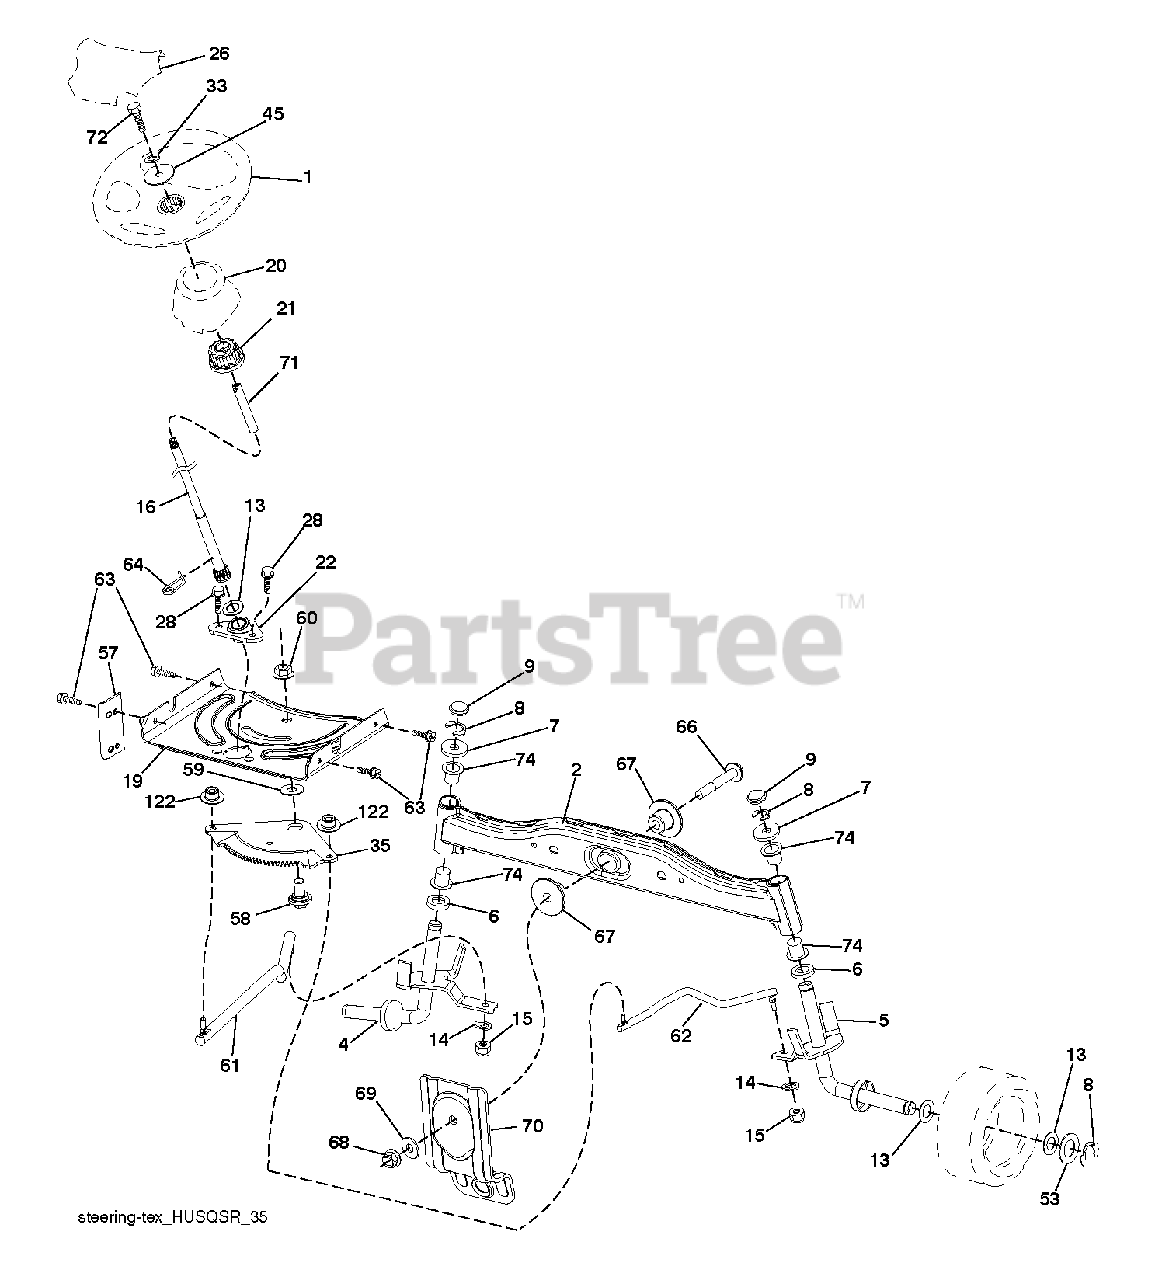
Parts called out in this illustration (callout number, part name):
1	WHEEL.STEER.HUSQ.SR.498.OVMLD
2	AXLE HALF ASM-WELDED
4	SPINDLE.STEERING.ASM.LH.13".TI
5	SPINDLE.STEERING.ASM.RH.13".TI
6	THRUST WASHER
9	CAP.SPINDLE.BLACK
14	WASHER, LOCK 3/8
15	NUT CROWNLOCK 3/8-24
16	SHAFT.STEER.3/4.PLATED.TEX
19	PLATE.STEER.DDL.NLT/NG
20	STEERING.BOOT.HUSQ.LT
21	ADAPTER, WHEEL STNG..
22	STEERING.SUPT.LOWER.
26	INSERT.CAP.WHL.STRG.HUSQ.PREM
28	SCREW, 3/8-16X3/4
33	LOCKWASHER
35	GEAR.SECTOR.PLATE.DDL.
45	WASHER.11/32
53	WASHER.HARDENED
57	BRACKET.UPSTOP.TEX
58	BOLT.SHOULDER.SECTOR.P
59	WASHER.THURST.SECTOR.S
60	NUT FLANGE LOCK 5/8-11
61	DRAGLINK.LH.BALLSTUD.D
62	DRAGLINK.RH.BALLSTUD.D
63	SCREW
64	RETAINER.CLIP.SPRING.S
66	BOLT HEX FGHD 7/16-14 X 3 SERR
67	BUSHING.PM.FRONT AXLE
68	NUT.LOCK.FLANGE.7/16
69	WASHER.1.5X.505X.118
70	BRACKET.SUSP.MWR.FRT.30"SRD
71	SHAFT.EXTEN.STRG.SPLINE
72	BOLT 5/16-18 X 4 W/PATCH
74	BRNG T
122	CAP.GEAR.SECTOR.TEX
